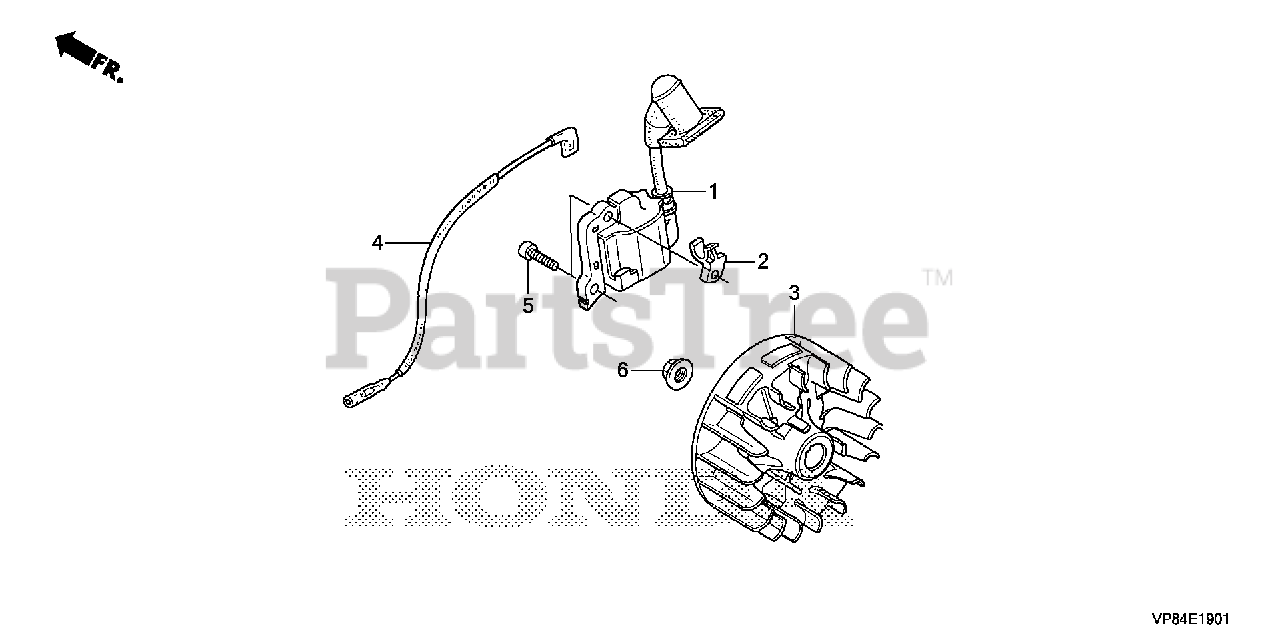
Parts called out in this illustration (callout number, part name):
1	COIL ASSY., IGNITION
2	CLIP, IGNITION WIRE
4	WIRE, STOP SWITCH
5	BOLT, SOCKET (4X14)
6	NUT, FLANGE (8MM)
